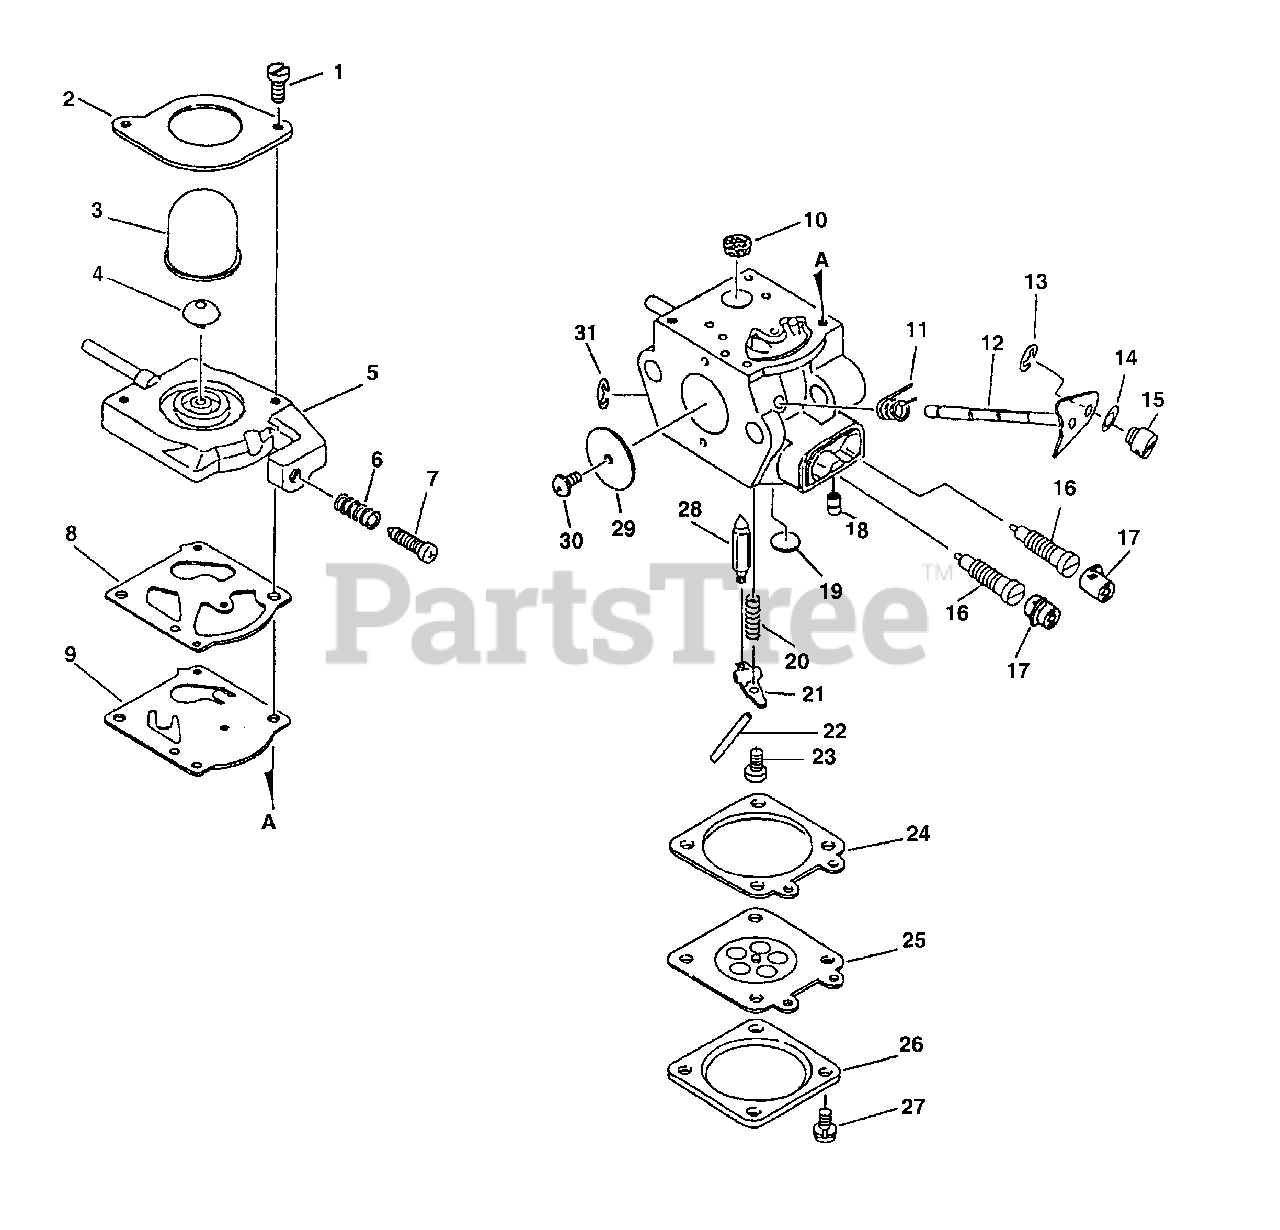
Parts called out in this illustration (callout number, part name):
1	SCREW, PUMP COVER
2	RETAINER, PURGE BULB
3	BULB, PURGE
4	VALVE, CHECK
5	BASE, PURGE
6	SPRING, IDLE ADJUST
7	SCREW, IDLE ADJUST
8	GASKET, PUMP
9	DIAPHRAGM, PUMP
10	STRAINER
11	SPRING, THROTTLE RETURN
12	SHAFT, THROTTLE
13	RING, RETAINING
16	NEEDLE - MIXTURE
17	CAP, LIMITER
18	NOZZLE, CHECK VALVE
19	PLUG, WELCH
20	SPRING, METERING LEVER
21	LEVER, METERING
22	PIN, METERING LEVER
23	SCREW, METERING LEVER PIN
24	GASKET, METERING
25	DIAPHRAGM, METERING
26	COVER, METERING
27	SCREW
28	VALVE, INLET NEEDLE
29	VALVE, THROTTLE
31	RING, RETAINING
